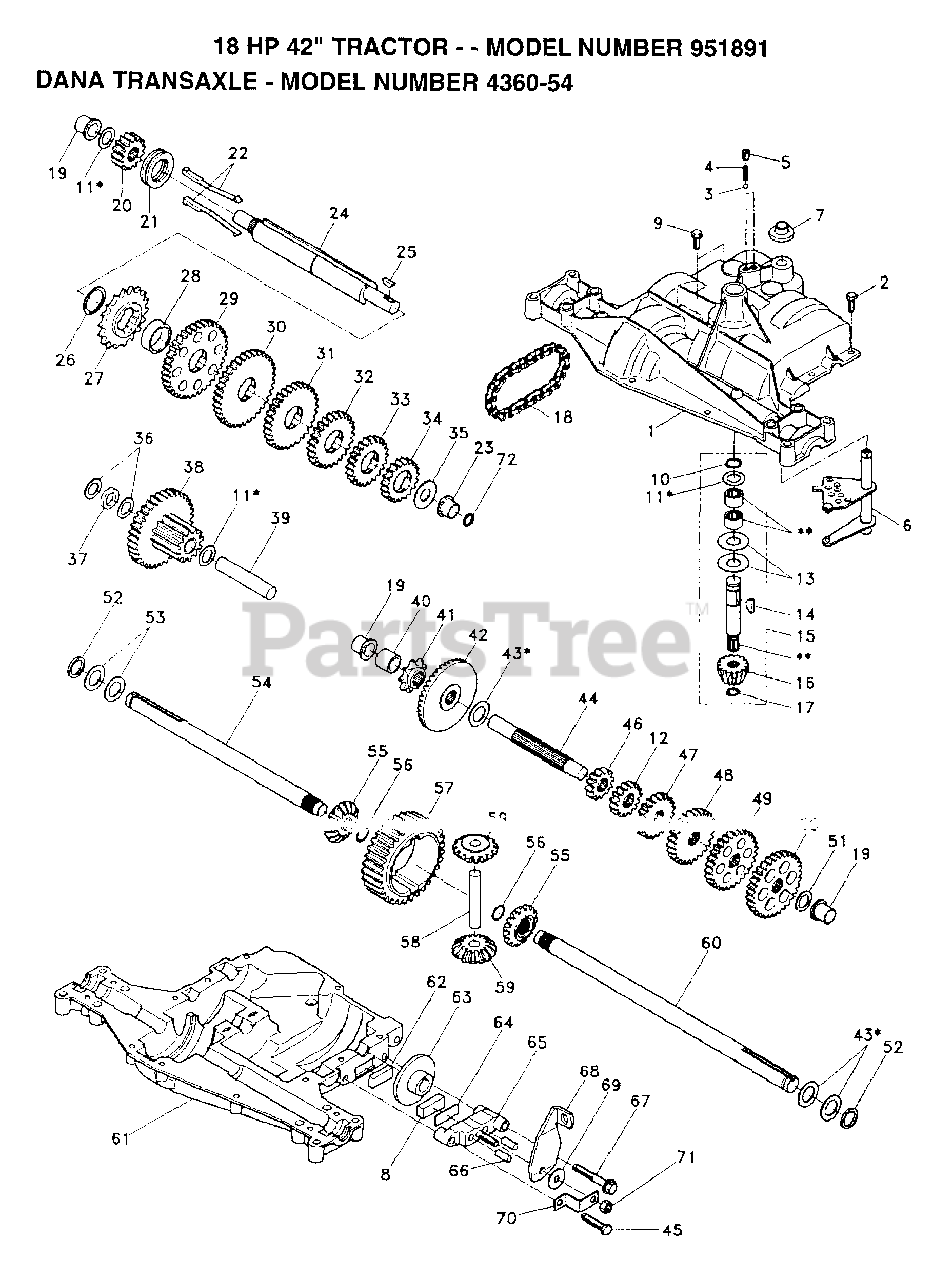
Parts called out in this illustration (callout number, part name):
4	"SPRING, DETENT LT"
5	"SCREW, SET LT"
6	SHIFTER.ASM.KIT.
7	SHIFTER BOOT
8	PUCK T
9	SCREW TAP W/SEAL
10	RETAINING RING LT
11	ASM KIT SHIM 4689
13	WASHER T
14	WOODRUFF KEY
17	"RING,RETAINING LT"
18	"CHAIN,24 PTCH LT"
19	BEARING.FLNG.5510
20	GEAR SPUR 14T
21	COLLAR CLUTCH
22	KIT.ASM.CLUTCH KY
23	"FLANGE, BEARING"
24	SHAFT INTERM
25	WOODRUFF KEY
26	"RING,RETAINING LT"
27	SPROCKET 18T T
28	SPACER YT
29	KIT.GEAR.12/37TH
31	GEAR SPUR 30T
32	GEAR 25T LT
33	GEAR SPUR 22 TT
34	SPUR GEAR 19T
35	"WASHER, PLAIN LT"
36	WASHER 025
37	SPACER
38	ASSM GEAR COMB
39	SHAFT IDLER
40	SPACER T
41	SPROCKET 9T LT
43	ASM KIT SHIM
44	SHAFT T
45	"SCREW, TAPPING LT"
48	"GEAR, SPUR 25T LT"
49	GEAR 28T T
50	"GEAR, SPUR 31T LT"
51	WASHER 060
52	NEOPRENE WASHER
53	WASHER 031
55	GEAR LT
56	"RING,RETAINING LT"
58	SHAFT T
59	"GEAR,MITER 15T YT"
62	PUCK T
63	BRAKE DISC. T
64	SPACER LT
66	PIN T
69	WASHER LT
71	NUT.LOCK.5/16-24
72	SQUARE RING
